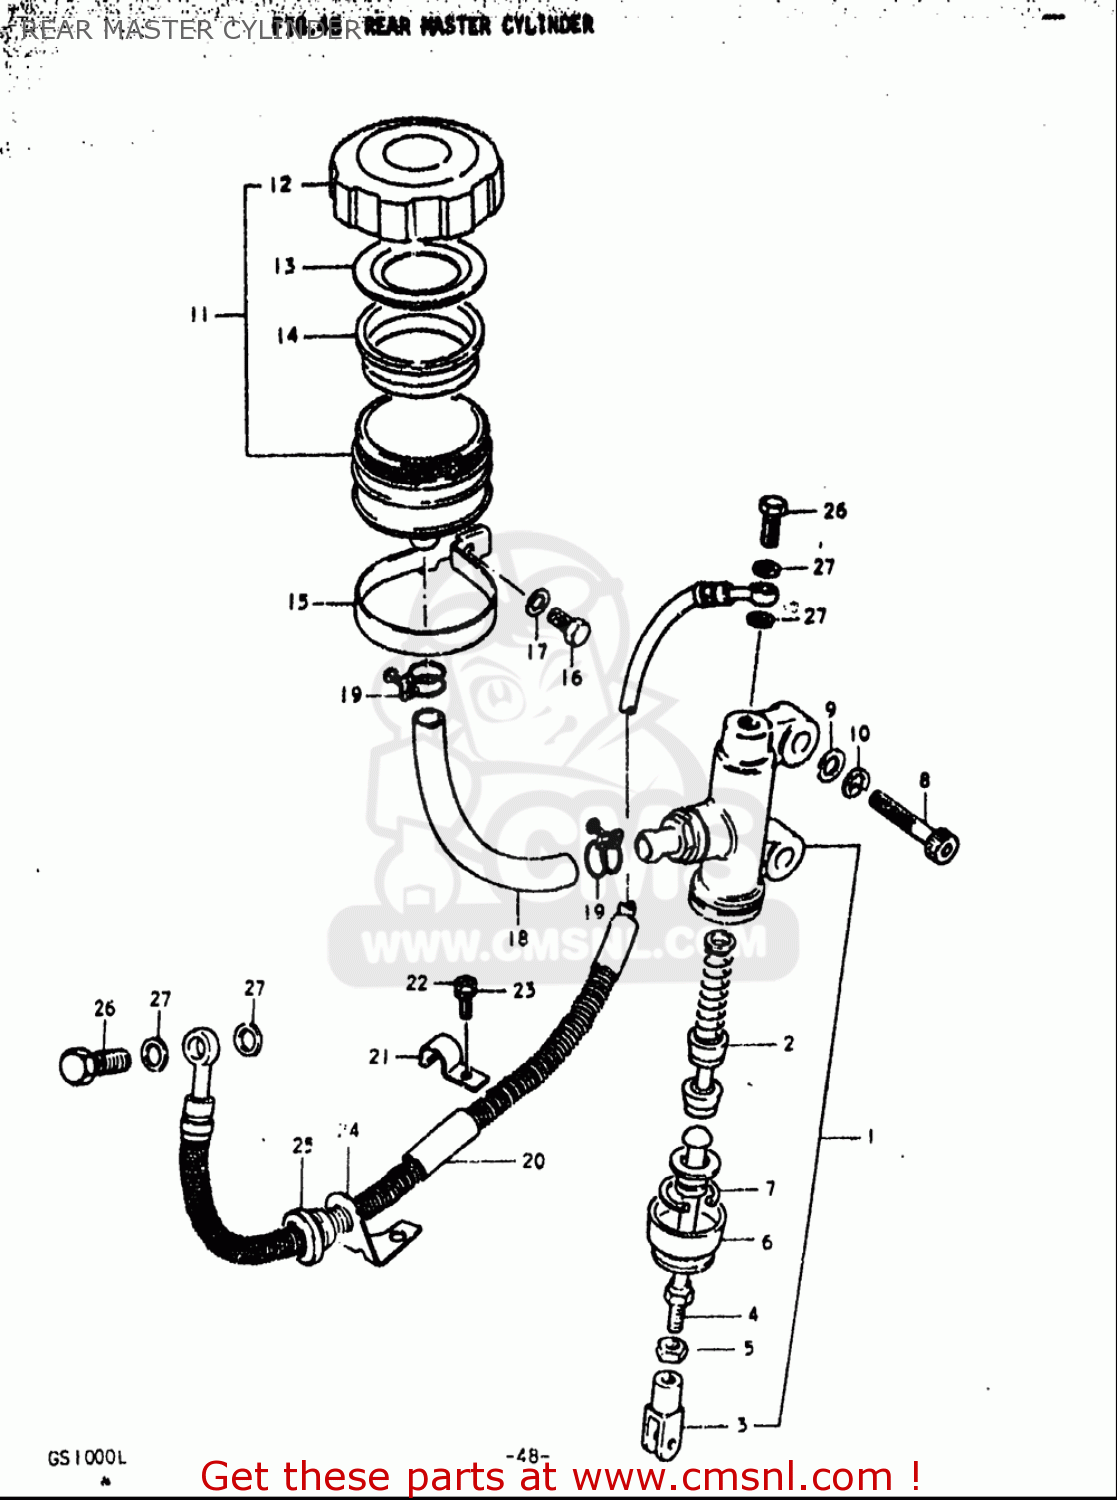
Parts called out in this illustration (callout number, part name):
1	CYLINDER ASSY,RR MASTER
2	PISTON/CUP SET
3	YOKE
4	ROD,PUSH
5	NUT
6	BOOT
7	CIRCLIP
8	BOLT
9	WASHER
10	WASHER,LOCK
11	TANK ASSY,RESERVOIR
12	CAP
13	PLATE,DIAPHRAGM
14	DIAPHRAGM
15	CLAMP
16	BOLT
17	WASHER,LOCK
18	HOSE,BRAKE RESERVOIR
19	CLAMP
22	SCREW(6X8)
23	WASHER,LOCK
24	GUIDE,BRAKE HOSE
25	GROMMET,BRAKE HOSE GUIDE
26	BOLT UNION
27	WASHER(10X15X1.5)
